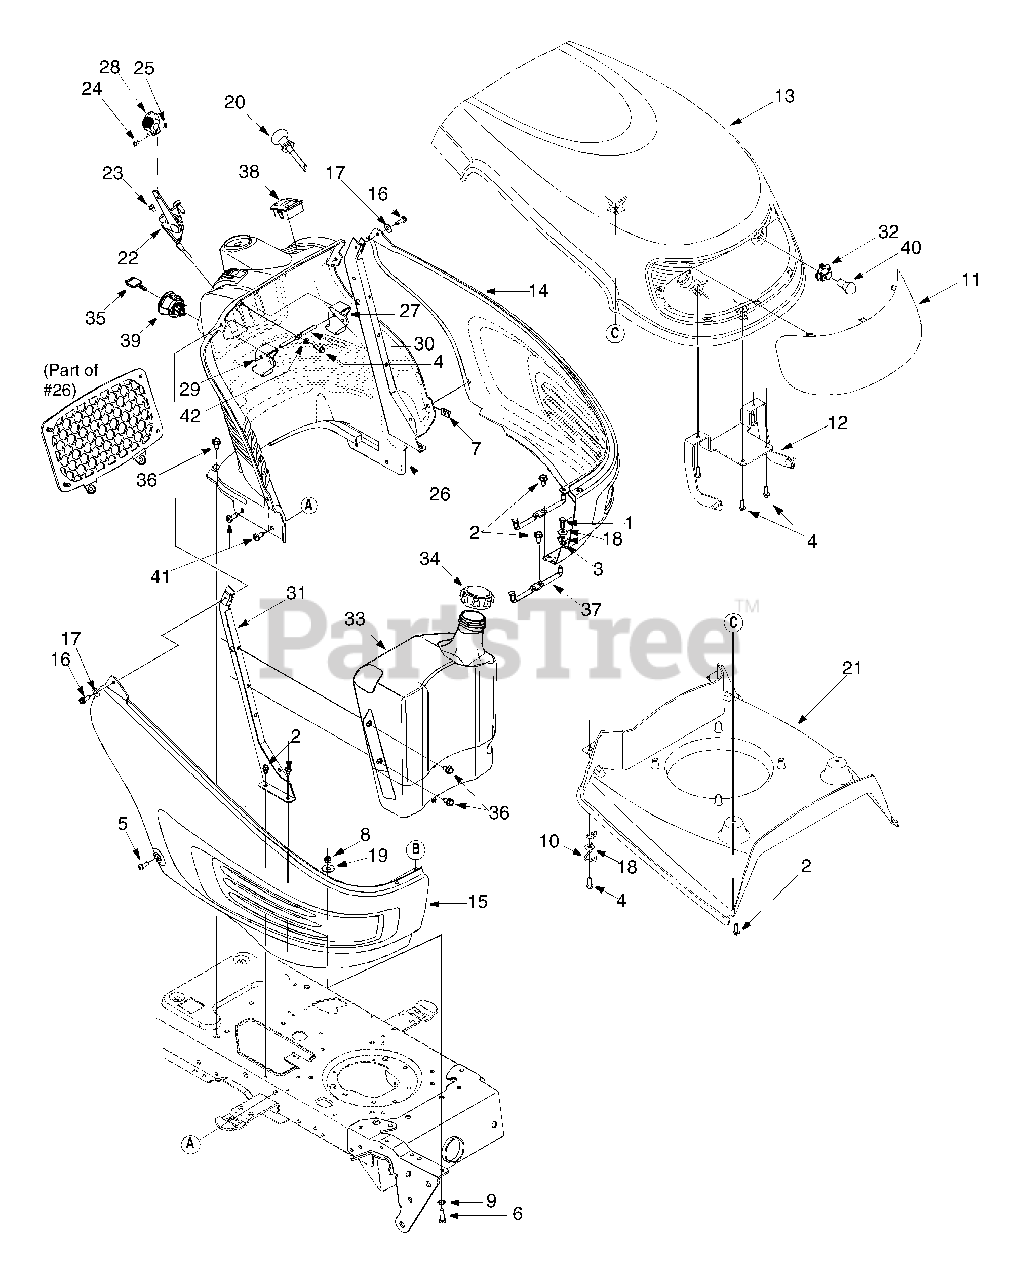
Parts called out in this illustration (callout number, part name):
1	Hex Cap Screw, 1/4-20 x.75
2	Self-tapping Screw, 1/4-20 x.5
3	Flange Lock Nut, 1/4-20
4	Self-tapping Screw, 1/4-15 x.75
5	Pan Phillips Screw, 1/4-20 x.75
6	Hex Cap Screw, 5/16-18 x 1.0
7	U-type Speed Nut, 1/4-20
8	Flange Lock Nut, 5/16-18
10	Hood Latch Rod
11	Head Light Lens
14	LH Side Panel
15	RH Side Panel
16	Screw, 1/4-20 x.750
17	Flat Washer,.283 x.75 x.030
18	Flat Washer,.28 x.74 x.063
19	Flat Washer,.349 x 1.0 x.063
20	Choke Control
21	Hood Plenum w/o Intake Bellow
22	Throttle Control/Cable
23	Torx Self-Tapping Screw, 1/4-14 x.625
24	Torx Screw, #8-32 x.375
25	Hex Nut, 8-32
26	Dash Panel, 4-style w/ Cargo Net
27	Parking Brake Button
28	Throttle Control Lever
29	Cruise Control Button
30	Brake/Cruise Pivot Rod
32	Lamp Socket
33	Fuel Tank, 3-gallon
34	Fuel Cap
35	Ignition Key w/ plastic cover
36	Self-tapping Screw, 5/16-18 x.75
37	Side Panel Support
38	Systems Indicator Monitor
39	Ignition Switch
40	Miniature Lamp, 12V
41	Self-tapping Screw, 5/16-18 x.75
